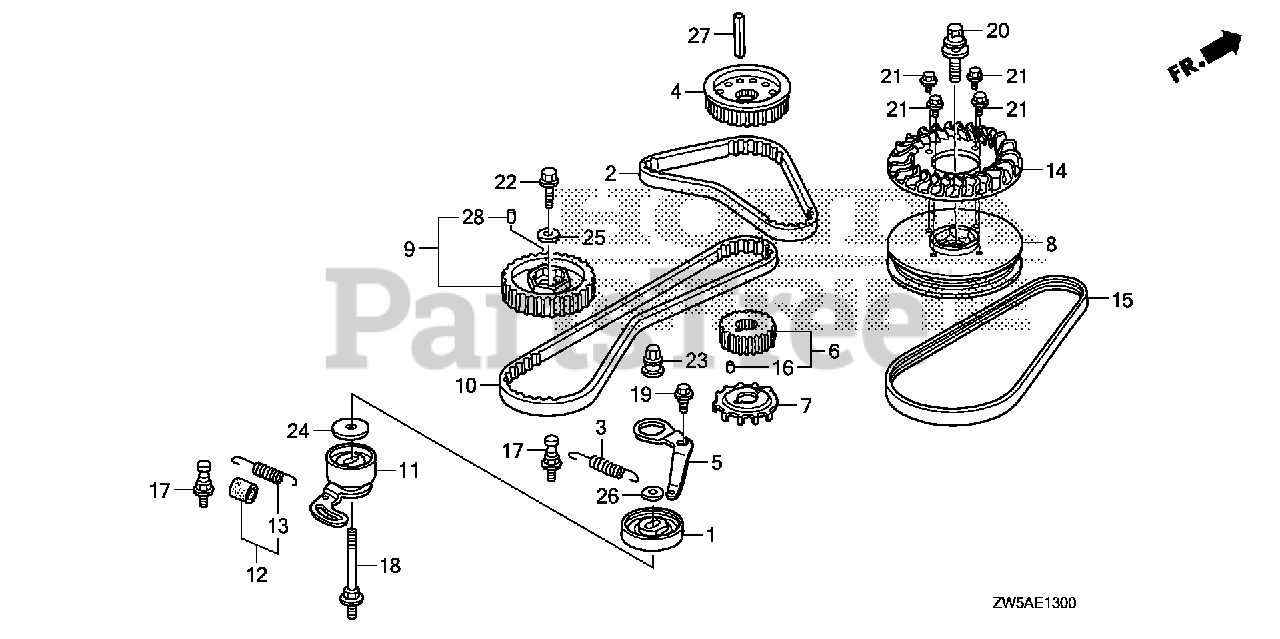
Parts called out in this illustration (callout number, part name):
1	TENSIONER, BALANCER BELT
2	BELT, BALANCER TIMING (UNITTA)
3	SPRING, BALANCER BELT ADJUSTER
4	PULLEY, BALANCER BELT DRIVE
5	BRACKET, B. BELT ADJUST
6	PULLEY, TIMING BELT DRIVE
7	PLATE, TIMING BELT GUIDE
8	PULLEY, CRANKSHAFT
9	PULLEY, TIMING BELT DRIVEN
10	BELT, TIMING (99RU24 B-333)
11	TENSIONER, TIMING BELT
12	SPRING, TIMING BELT ADJUSTER
13	SPRING, TIMING BELT ADJUSTER
14	FAN, COOLING
15	BELT, ALTERNATOR (4PK720 M150)
16	PIN, VERTICAL SHAFT
17	BOLT, TIMING BELT ADJUSTING SPRING
18	BOLT, TIMING BELT ADJUSTER
19	BOLT, BALANCER BELT ADJUSTER BRACKET
20	BOLT-WASHER (16X49)
21	BOLT, FLANGE (6X16)
22	BOLT, FLANGE (12X38)
23	NUT (10MM)
24	WASHER (10.5X44)
25	WASHER (12.5X34X5)
26	WASHER (10.3X25)
27	KEY (4.5X38.5)
28	ROLLER (4X10)
